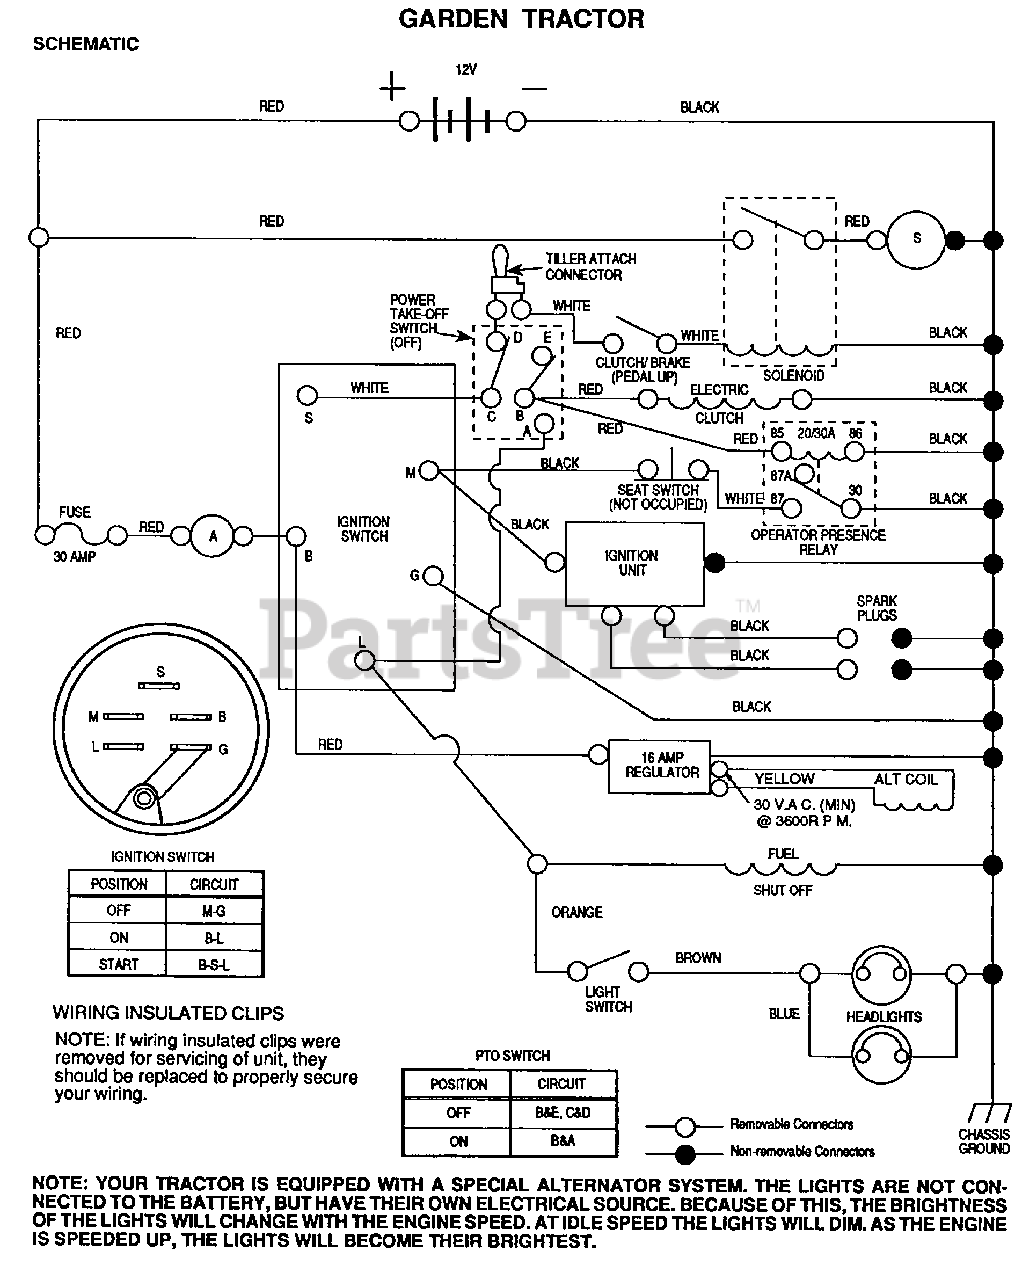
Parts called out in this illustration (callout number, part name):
6	LOWER DASH
8	SUPPORT RH YTH
11	CONSOLE SHIFTER
12	DECAL HOOD LH
17	LENS LT
18	SUPPORT LH YTH
21	SUPPORT RH YTH
23	SUPPORT LH YTH
27	CHASSIS ASSY
28	DRAW BAR
29	WASHER
30	BUSHING
31	PANEL DASH LH
32	FOOTREST LH YT
37	LOCKWASHER GT
38	"WASHER,LOCK"
40	REFLECTOR-TAIL YT
41	SPRING COMPRESSIO
44	BOLT
46	DECAL T
47	PLUG BUTTON T
49	NUT
51	WASHER
53	BOLT
54	SCREW
56	"""J"" FASTENER LT"
57	SCREW
58	SPACER
59	SCREW
61	STUD.1/4.TURN
63	SPRING
65	SCREW LT
68	RETAINER LT
69	RECEPTACLE LT
73	BOLT
76	SCREW
78	SCREW
79	DECAL
81	COVER ACCESS
82	WASHER
84	BOLT
85	PAD FOOTREST T
86	SCREW
87	LOCKWASHER
88	WELDNUT
89	HOOD LATCH T
90	SCREW
91	SPACER LT
96	NUT-PUSH YT
97	WASHER
99	VERTICAL BAFFLE
103	WASHER
104	SNAP BUSHING T
108	STRIP - FOAM
111	LOCKWASHER
112	WASHER PM
115	WASHER
117	CLIP T
118	WASHER
119	STRIP FORM
121	SPACER SPLIT
125	"NUT,KEPS"
127	BRKT SWITCH
